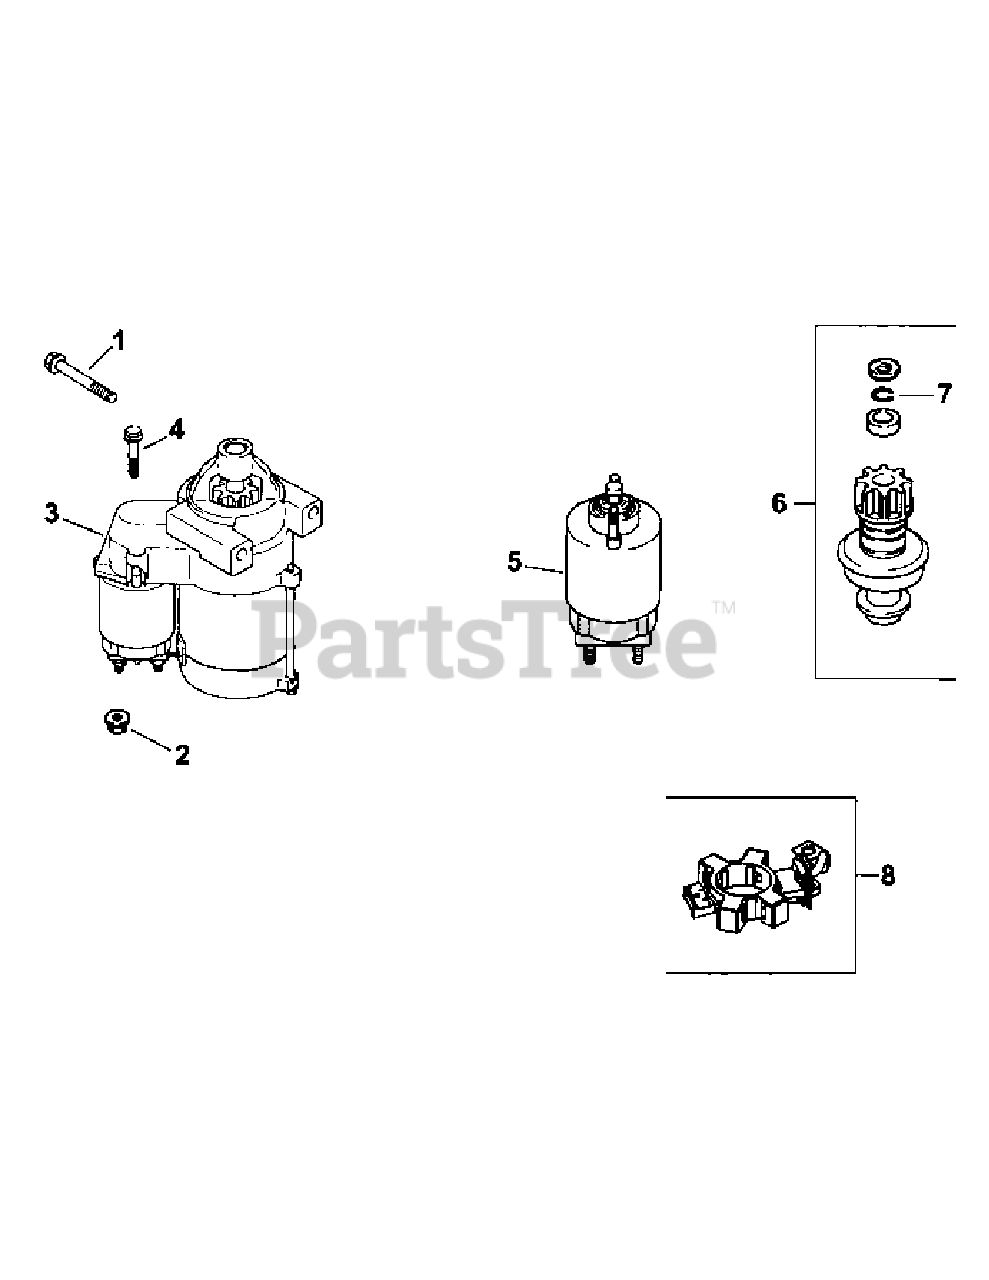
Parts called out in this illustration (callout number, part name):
1	Hex Flange Screw (M8 x 1.25 x 80)
2	Hex Flange Nut (M8 x 1.25)
3	Solenoid Shift Starter
4	External Torx Head Screw
5	Solenoid Kit
6	Starter Pinion Kit
